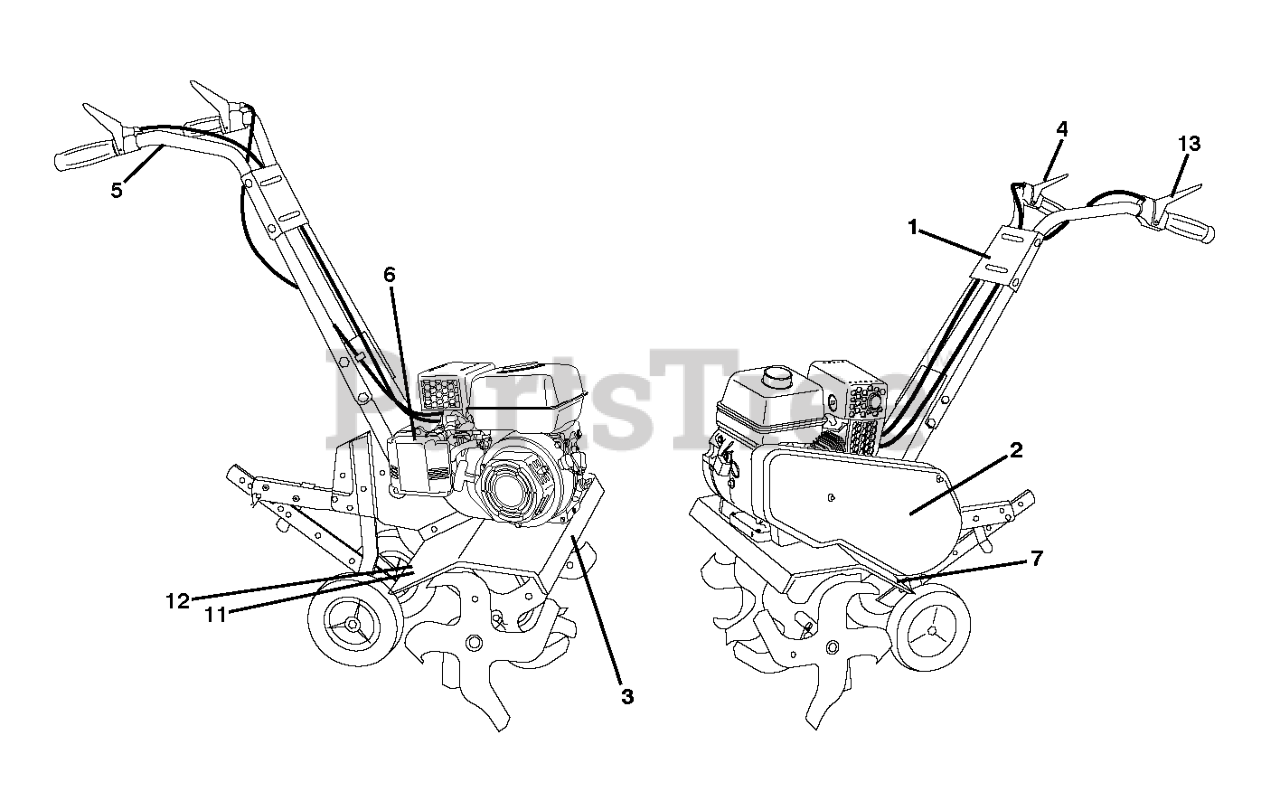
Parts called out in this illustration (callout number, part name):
1	DECAL.CONSOLE.DBBND.FT900.HUSQ
2	RP.DECAL.BADGE.170MM.TEXTLOGO
3	DECAL.TINESHIELD.FTT.26".HUSQ.
4	DECAL
6	DECAL.TILLER.LCT.900
7	DECAL.FENDER
12	DECAL.TINE.SHIELD
13	DECAL
